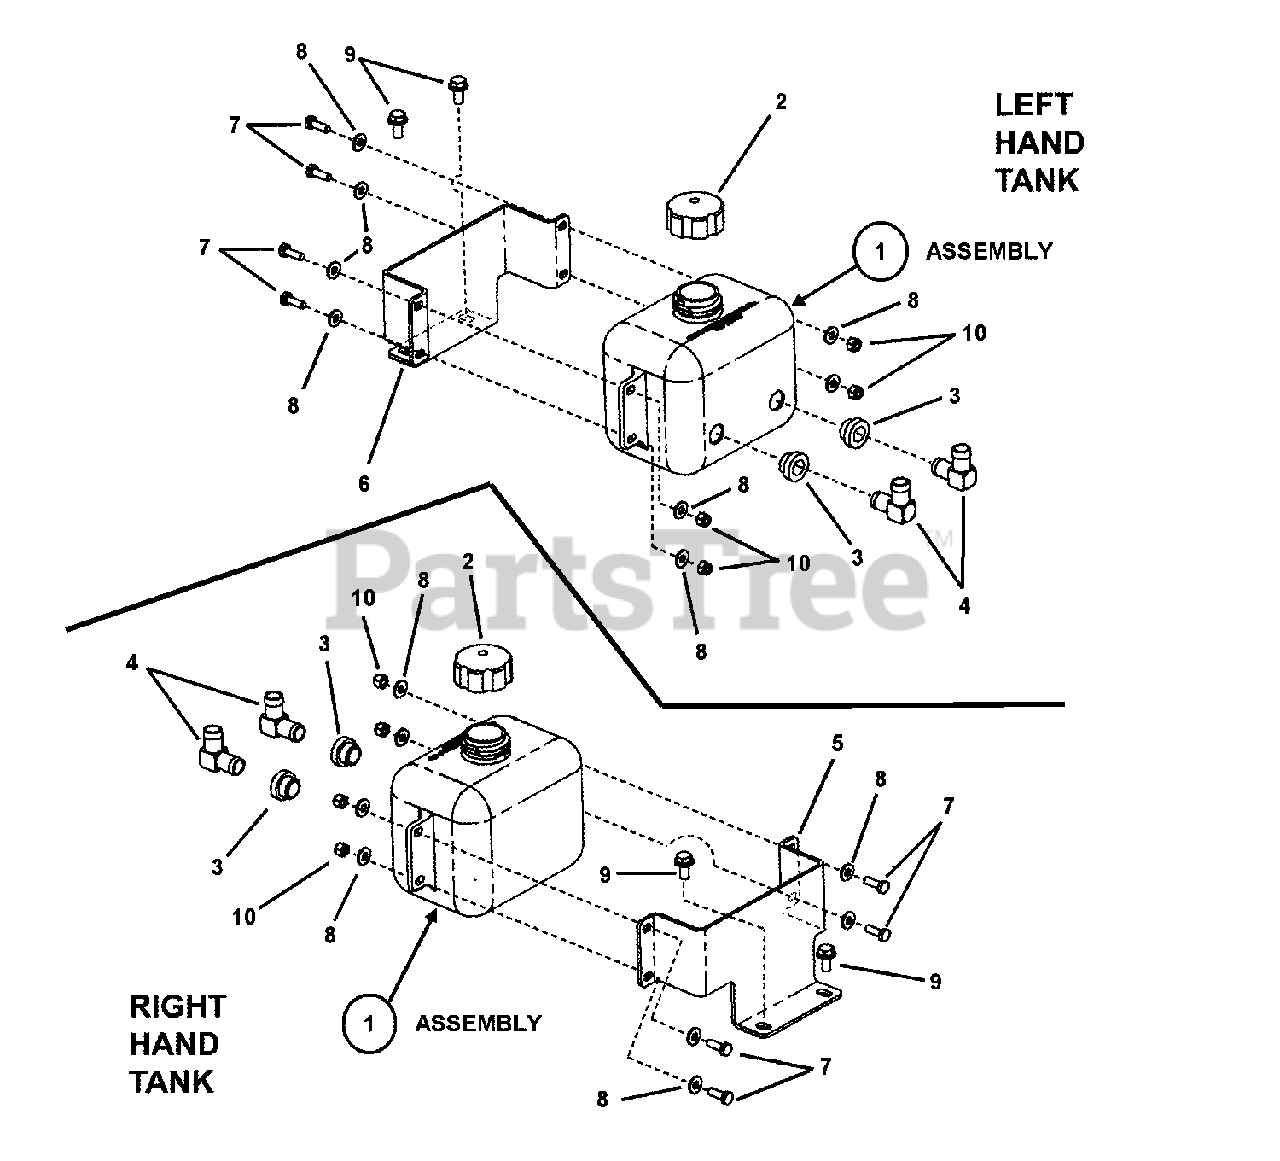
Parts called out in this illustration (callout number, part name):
1	ASSY, Hydraulic Tank (Incl. tank, p/n 74002 and indented items below)
2	CAP, Vented (Kelck p/n H4550D)
3	GROMMET (was 12337)
4	FITTING, #8 Elbox
5	BRACKET, R.H. Hydro Tank Mount
6	BRACKET, L.H. Hydro Tank Mount
7	BOLT, 1/4-20 X 1" GD5 CZ
8	WASHER, 1/4" Flat
9	SCREW, 5/16-18 x 5/8" Hex Washer Self-Tap
10	NUT, 1/4-20 HEX NYLON LOCK
